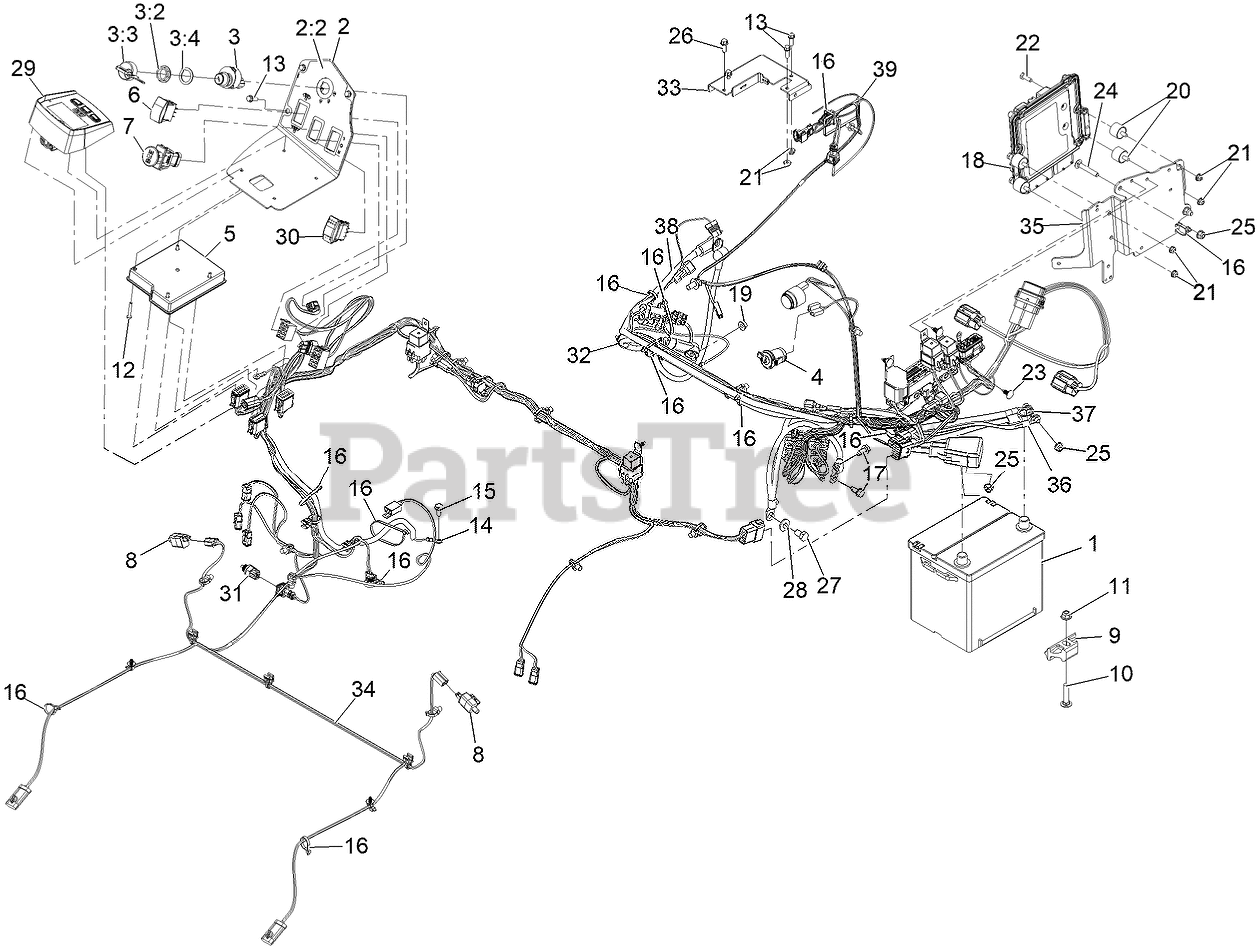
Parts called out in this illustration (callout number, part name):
1	Battery-Dry
2	ASM, CONSOLE W/ DECAL 144
2:2	DECAL-CONTROL PANEL
3	IGNITION SWITCH ASM
3:2	NUT-MOUNTING
3:3	IGNITION KEY SET
3:4	WASHER-BACKUP
4	PORT-POWER, 12V
5	Module-Mcu
7	SWITCH-PTO, SEALED
9	RETAINER-BATTERY
10	SCREW-CARR
11	NUT-HF, NI
12	SCREW-PPH
13	SCREW-HWH
14	HARNESS-WIRE, JUMPER
15	BOLT
16	TIE-CABLE
17	Screw-HWH 5/16-18 X 3/4 Tf
18	Electronic Control Unit
20	MOUNT-CYLINDRICAL
22	SCREW-HH
23	PLUG-PLASTIC
24	BOLT-CARR
25	NUT-HF, NI
26	SCREW-HHF
27	SCREW-HH
28	WASHER-BELLEVILLE
29	MODULE, LDU
30	SWITCH-ROCKER, ON-NONE-ON
31	SENSOR-TEMPERATURE
32	CLIP-TIE
33	BRACKET-SENSOR, DPF
34	HARNESS-WIRE, MAIN
35	PLATE-ECU MOUNT
36	HARNESS-WIRE, ENGINE
37	CABLE-BATTERY, RD AND BK ASM
38	CABLE-BATTERY, BK ASM
39	TIE-CABLE
